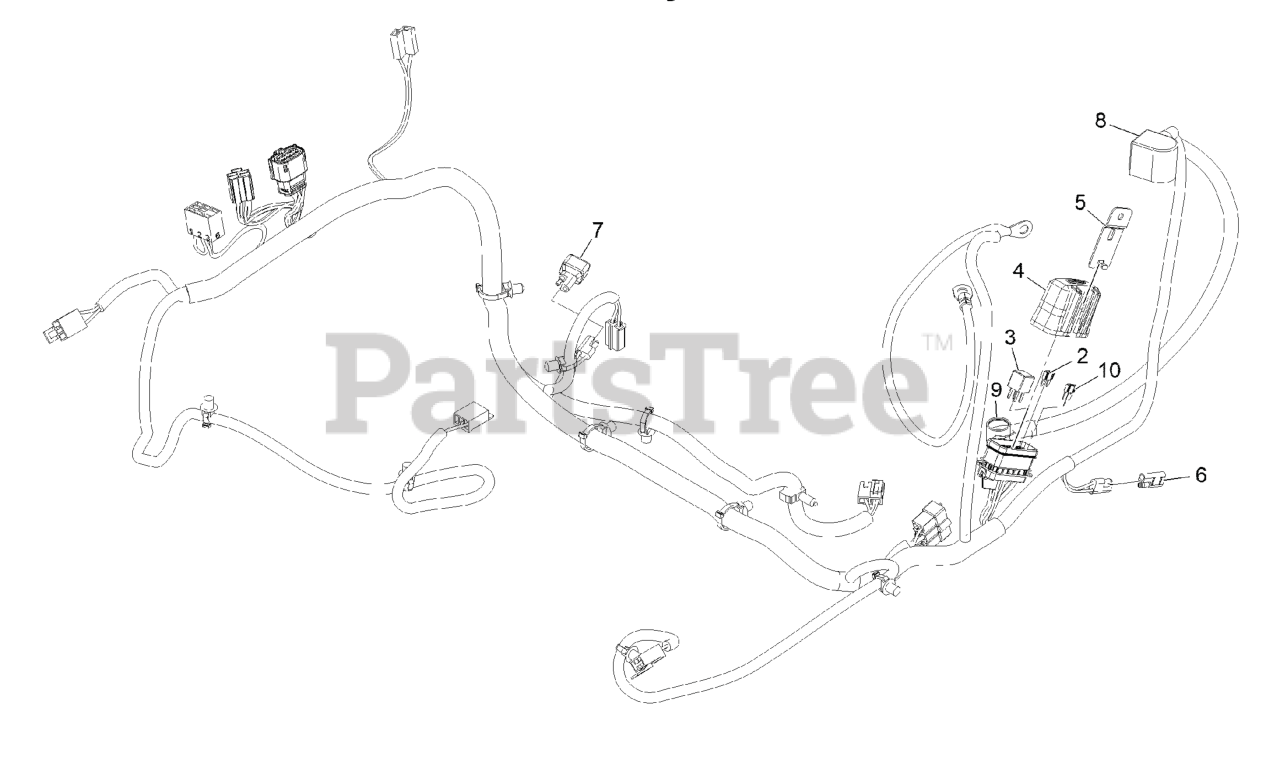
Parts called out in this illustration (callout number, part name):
2	FUSE-MINI BLADE, 20 AMP
3	RELAY-MICRO
4	COVER-BLOCK, FUSE
5	CLIP-MOUNTING
6	CAP-PLUG
8	INSULATOR-BATTERY
9	INSULATOR-SOLENOID
10	FUSE-MINI BLADE, 15 AMP
